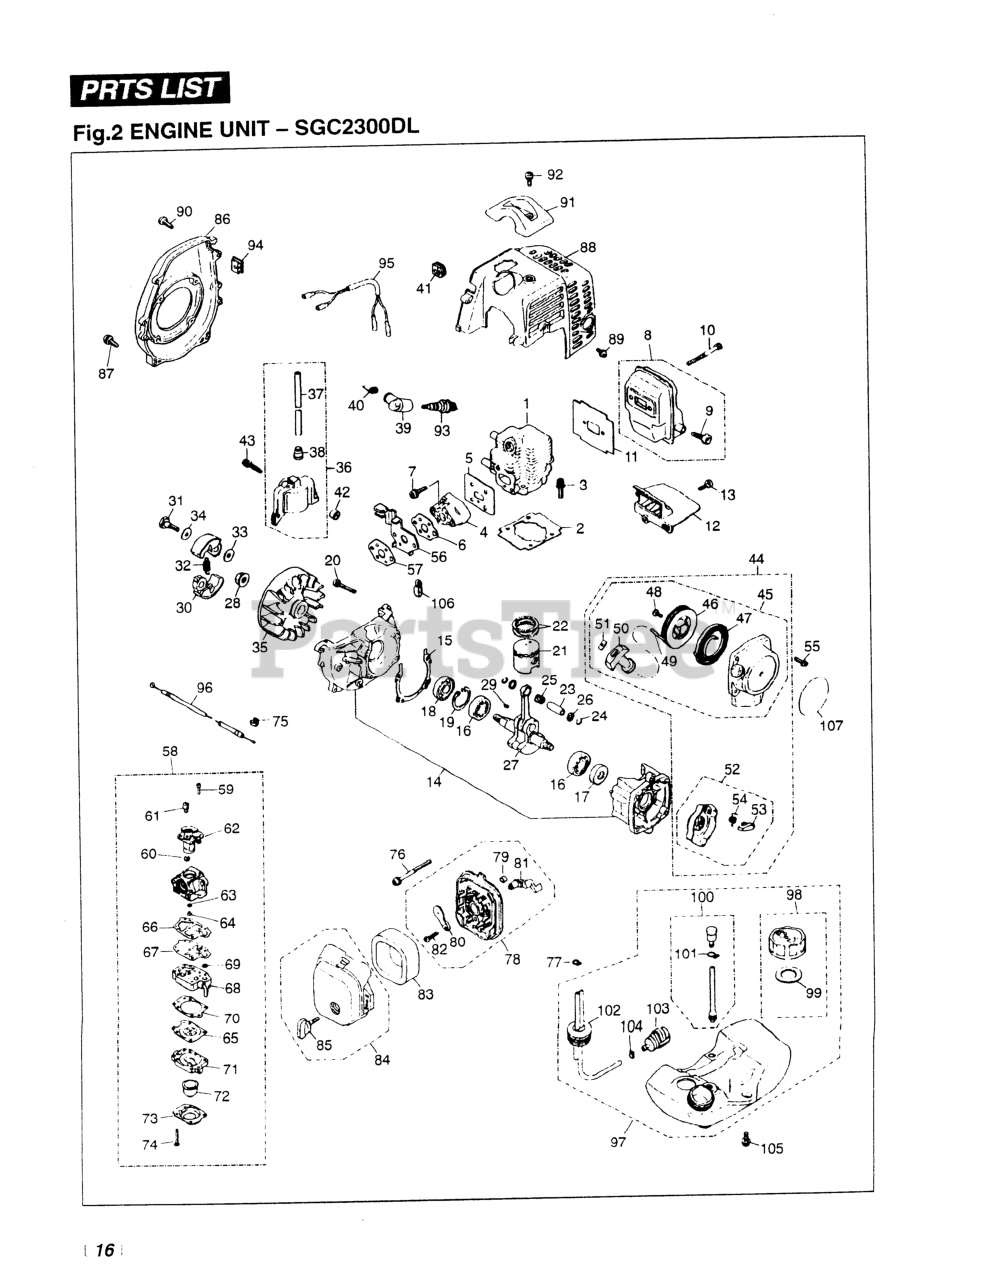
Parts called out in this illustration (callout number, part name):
1	CYLINDER
3	BOLT, M5 X 22
7	SCREW, M5X20 (RPLS.1400-75510)
8	MUFFLER ASSY (RPLS 5501- )
10	BOLT, M5 x 50
11	GASKET, MUFFLER
13	SCREW, M4 X 16
14	CRANKCASE
16	BEARING
17	SEAL, OIL (RPLS 1100-21210)
18	SEAL, OIL (RPLS 1140-21220)
19	RING, SNAP, M28 x 1.2
20	BOLT, M5 X 30
21	PISTON (REPLACES 1140-41110)
22	RING, PISTON (RPLS 1850-41210)
23	PIN, PISTON 5x8x26
24	RING, SNAP (RPLS 1101-41320)
26	WASHER
27	CRANKSHAFT (RPLS 1850-42000)
29	KEY
30	SHOE (RPLS 1100-51114)
31	BOLT
32	SPRING, CLUTCH (RPLS-51220)
33	WASHER, FLAT (USE 182303)
35	ROTOR (SGC2300)
37	CORD
40	SPRING
41	GROMMET
42	SPACER (RPLS -71260)
43	BOLT
45	RECOIL ASSEMBLY
46	REEL
47	SPRING, SPIRAL
48	SCREW (RPLS -75150)
50	KNOB
51	PLATE, STOPPER
52	PULLEY ASSY (RPLS -75210)
53	RATCHET (RPLS 1850-75220)
54	SPRING, RETURN
55	SCREW, M4 X 16
56	BRACKET
58	CARBURETOR
60	RING
61	SWIVEL
62	VALVE ASSY
63	RING, O
65	DIAPHRAGM (USE 4810-81260)
66	GASKET, PUMP
67	DIAPHRAGM
68	BODY, PUMP
70	GASKET, DIAPHRAGM
71	BODY, PURGE
72	PUMP, PRIMING
73	COVER, PUMP
74	SCREW
75	CAP, CABLE END
76	SCREW, M5 x 60
77	CLIP
78	BODY-A (RPLS -82101)
79	SLEEVE
80	PLATE, CHOKE (RPLS-82130)
81	LEVER, CHOKE
82	SCREW (REPLACES 50030272)
83	ELEMENT
85	KNOB (RPLS -82220)
86	COVER, FAN (RPLS-31110)
87	SCREW, M5X20 (RPLS.1400-75510)
89	SCREW, M5 x 12
90	SCREW, HOUSING
91	GUARD, PLUG
92	SCREW,M5 X 14 (RPLS 1400-15510
95	CORD COMP (RPLS -73200)
96	CABLE COMP (RPLS 1633-83100)
98	CAP (RPLS -85200)
99	PACKING
101	CLIP
102	PIPE COMPLETE
103	FILTER ASSY
104	CLIP (REPLACES 2841-31280)
105	SCREW
106	CLAMP
107	LABEL, RECOIL
